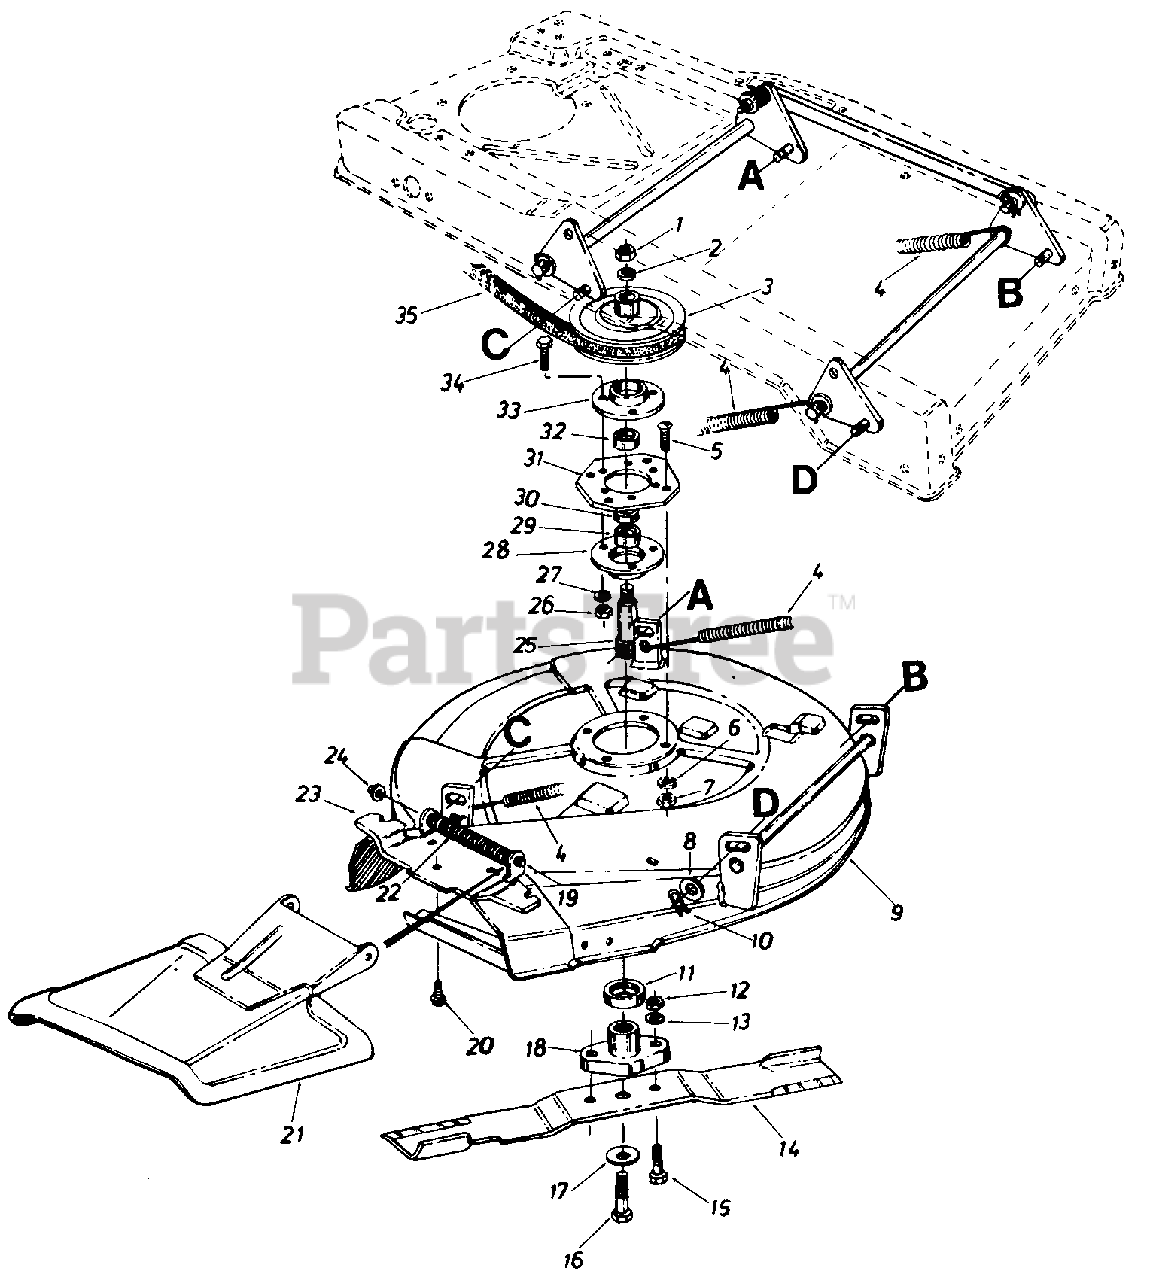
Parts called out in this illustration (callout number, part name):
1	Hex Jam Nut 5/16-18 Thd.
2	Bell-Wash. .630" I.D. x 1.25" O.D.
3	5/8" "V"-Pulley .75" I.D. x 9.5"
4	Extension Spring .56" O.D. x 1 0.5
5	Hex Bolt 5/16-18 x .75" Lg.
6	L-Wash. 5/16" I.D.
7	Hex Nut 5/16-18 Thd.
8	Fl-Wash. .510" I.D. x 1.0" O.D.
9	26" Deck Ass'y.
10	Inter. Cotter Pin 1/2" Dia.
11	Bearing Shield
12	Hex Nut 5/16-24 Thd.
13	L-Wash. 5/16" I.D.
14	Blade 26"
15	Hex Bolt Special 5/16-24 x 1.0" Lg.
16	Hex Bolt 3/8-24 x 1.00" Lg.
17	Bell-Wash. .391" I.D. x 1.38" O.D.
18	Blade Adapter
19	Hinge Pin
20	Hex Wash. Hd. TT-Scr. 1/4-20
21	Chute Cover Ass'y.
22	Torsion Spring
23	Adapter Plate
24	Cap Speed Nut 1/4" Rod
25	Blade Spindle 4.42" Lg.
26	Hex Nut 5/16-18 Thd.
27	L-Wash. 5/16" I.D.
28	Bearing Housing 1.85
29	Ball Brg. .787" I.D. x 1.85" O.D.
30	Spacer 1.0" O.D. x .790" I.D. x.350" Lg.
31	Spindle Mounting Plate
32	Ball Brg. .787" I.D. x 1.85" O.D.
33	Open Brg. Housing 1.85
34	Hex Bolt 5/16-18 x .75" Lg.
35	"V"-Belt
